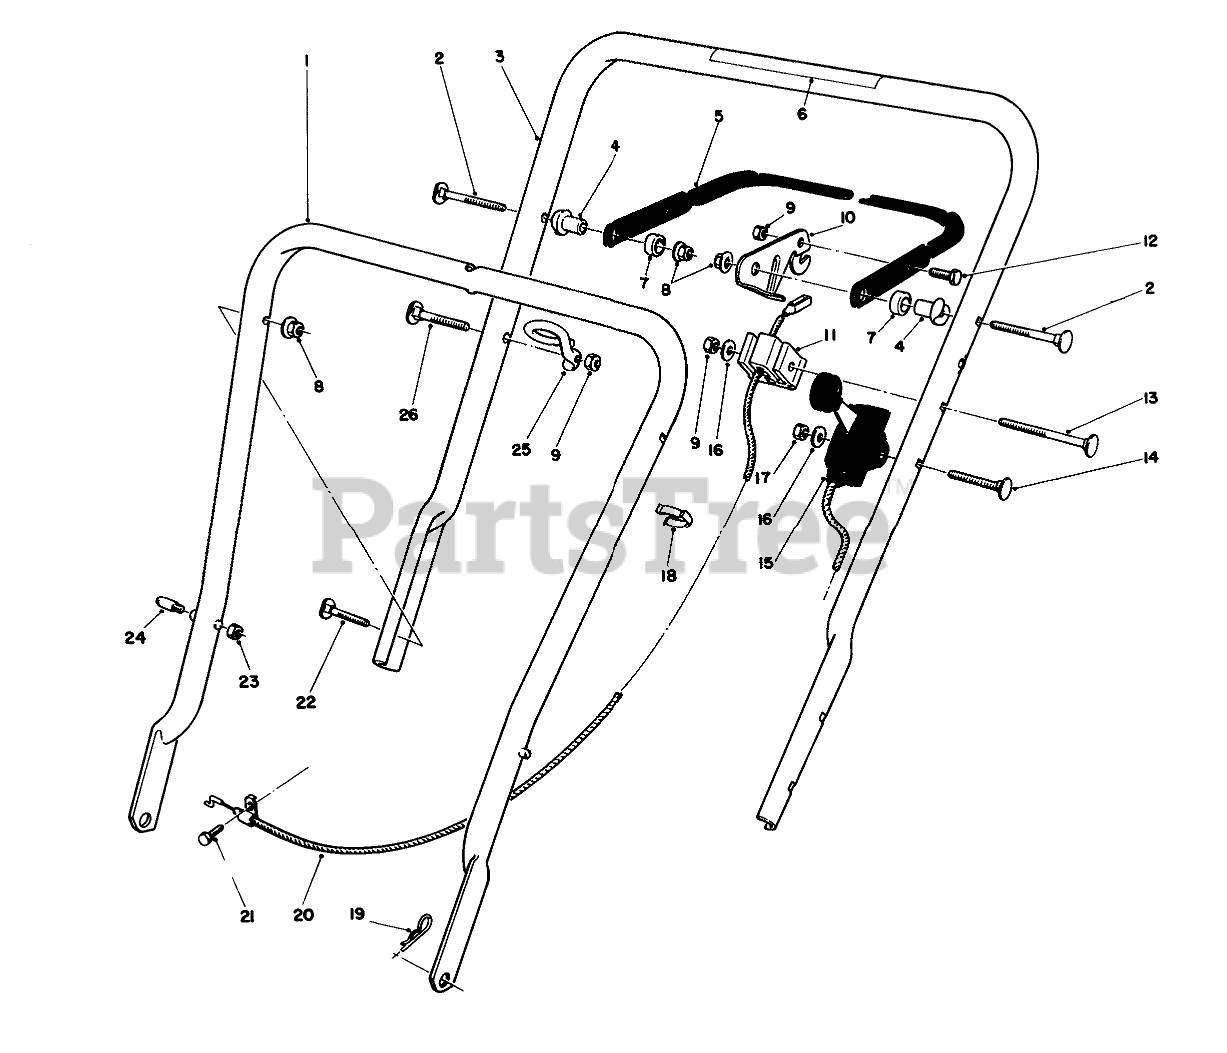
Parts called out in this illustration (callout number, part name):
1	LOWER HANDLE ASM
2	5/16-18 X 2 HNDLE SCREW
3	Handle-Upper (Incl. Ref. #6)
4	SPACER-SUPPORT
5	Bar-Control
6	DECAL - HANDLE
7	SPACER-NYLON
8	NUT-LOCK, NI
9	NUT-LOCK, NI
10	LEVER-CONTROL
11	SUPPORT-CABLE
12	SCREW-HH
13	HANDLE SCREW
14	SCREW-HANDLE
15	THROTTLE CONTROL
16	WASHER-FLAT
17	NUT-LOCK, NI
18	BOWDEN CLIP
19	PIN-COTTER, HAIR
20	BRAKE CABLE
21	SCREW-HH
22	SCREW
23	NUT-LOCK, NI
24	HANDLE PIN
25	Guide
26	HANDLE SCREW
